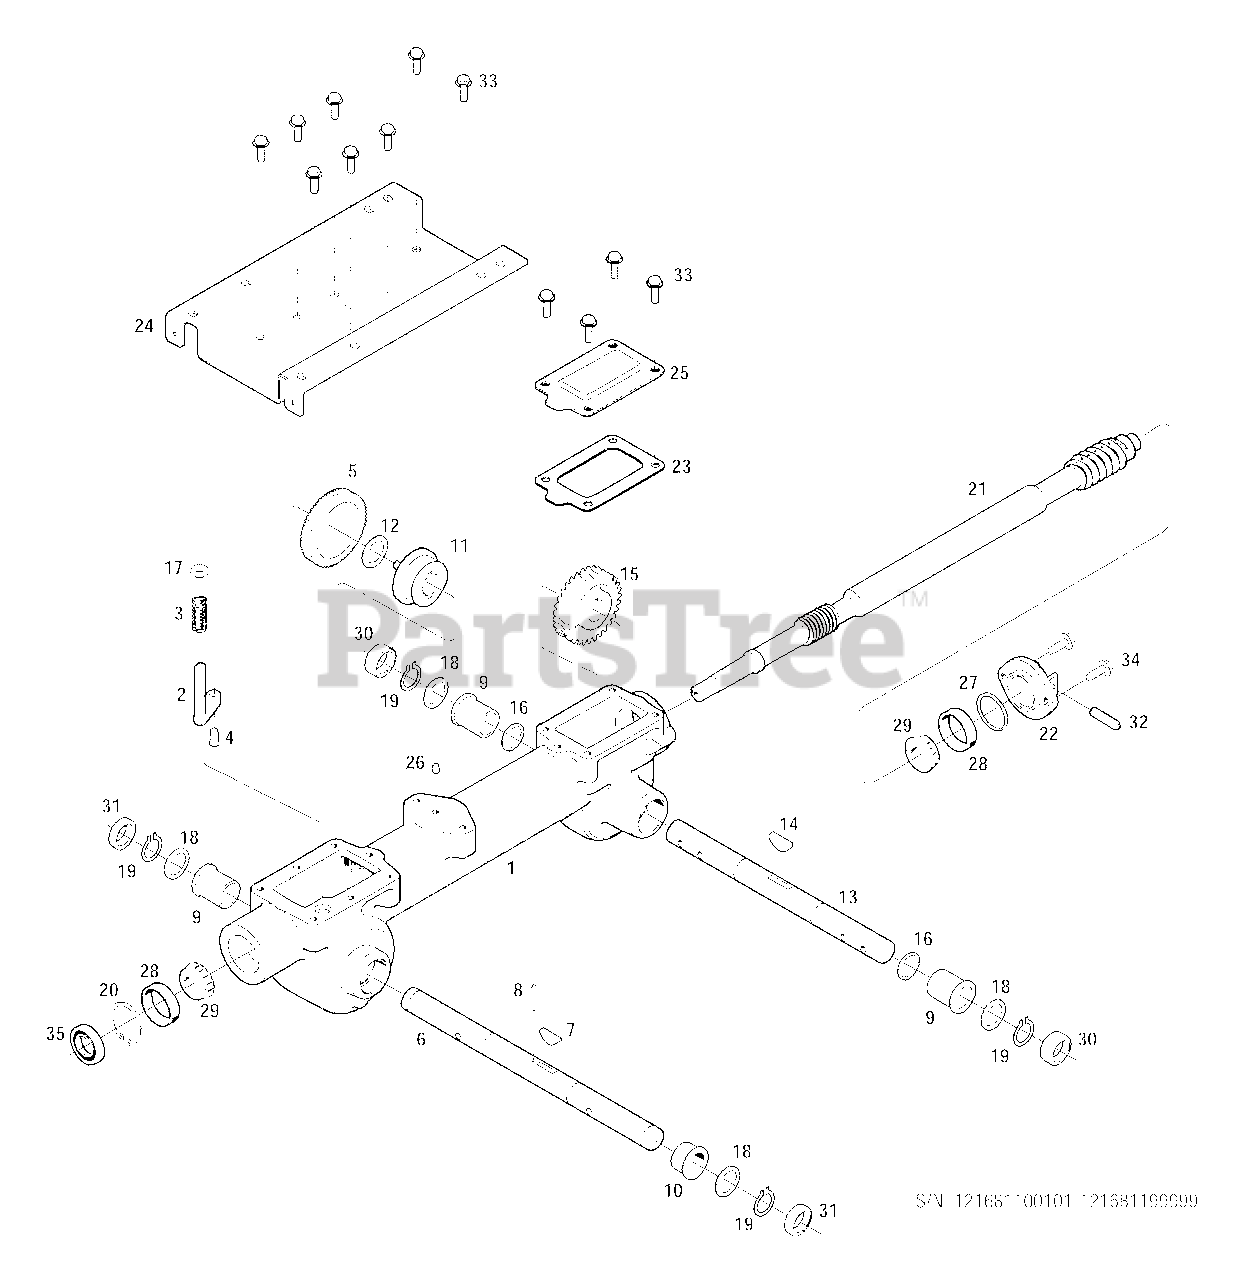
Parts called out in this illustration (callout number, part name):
1	Transmission Housing
2	Eccentric Shaft
3	Spring, Compression
4	Pin, .375 x .720
5	Gear, Wheel Drive
6	Wheel Shaft
7	Key, High Profile
8	Spring Pin
9	Bushing, Long
10	Bushing, Short
11	Wheel Drive Clutch
12	Washer, Thrust 1.468 x 1.016 x .062
13	Shaft, Tiller
14	Key, Woodruff
15	Worm Gear
16	Shim, 1.234 x 1.015
17	Seal, Eccentric
18	Shim, 1.375 x 1.015
19	Retaining Ring, External .906
20	Retaining Ring, Internal 1.812
21	Drive Shaft
22	Rear Bearing Cap
23	Gasket-Rear Housing
24	Transmission Cover/Front
25	Transmission Cover/Rear
26	Vent Plug
27	Shim, 1-3/4 x 1-1/2
28	Cup, Tapered Roller Bearing
29	Cone, Tapered Roller Bearing
30	Oil Seal-Tine Shaft
31	Oil Seal-Wheel Shaft
32	Spring Pin, 3/8
33	Screw, Hex Flange 5/16-18 x 7/8 Whiz Lock Thread Forming
34	Screw, Hex Flange, 5/16-18 x 1
35	Oil Seal, Drive Shaft
